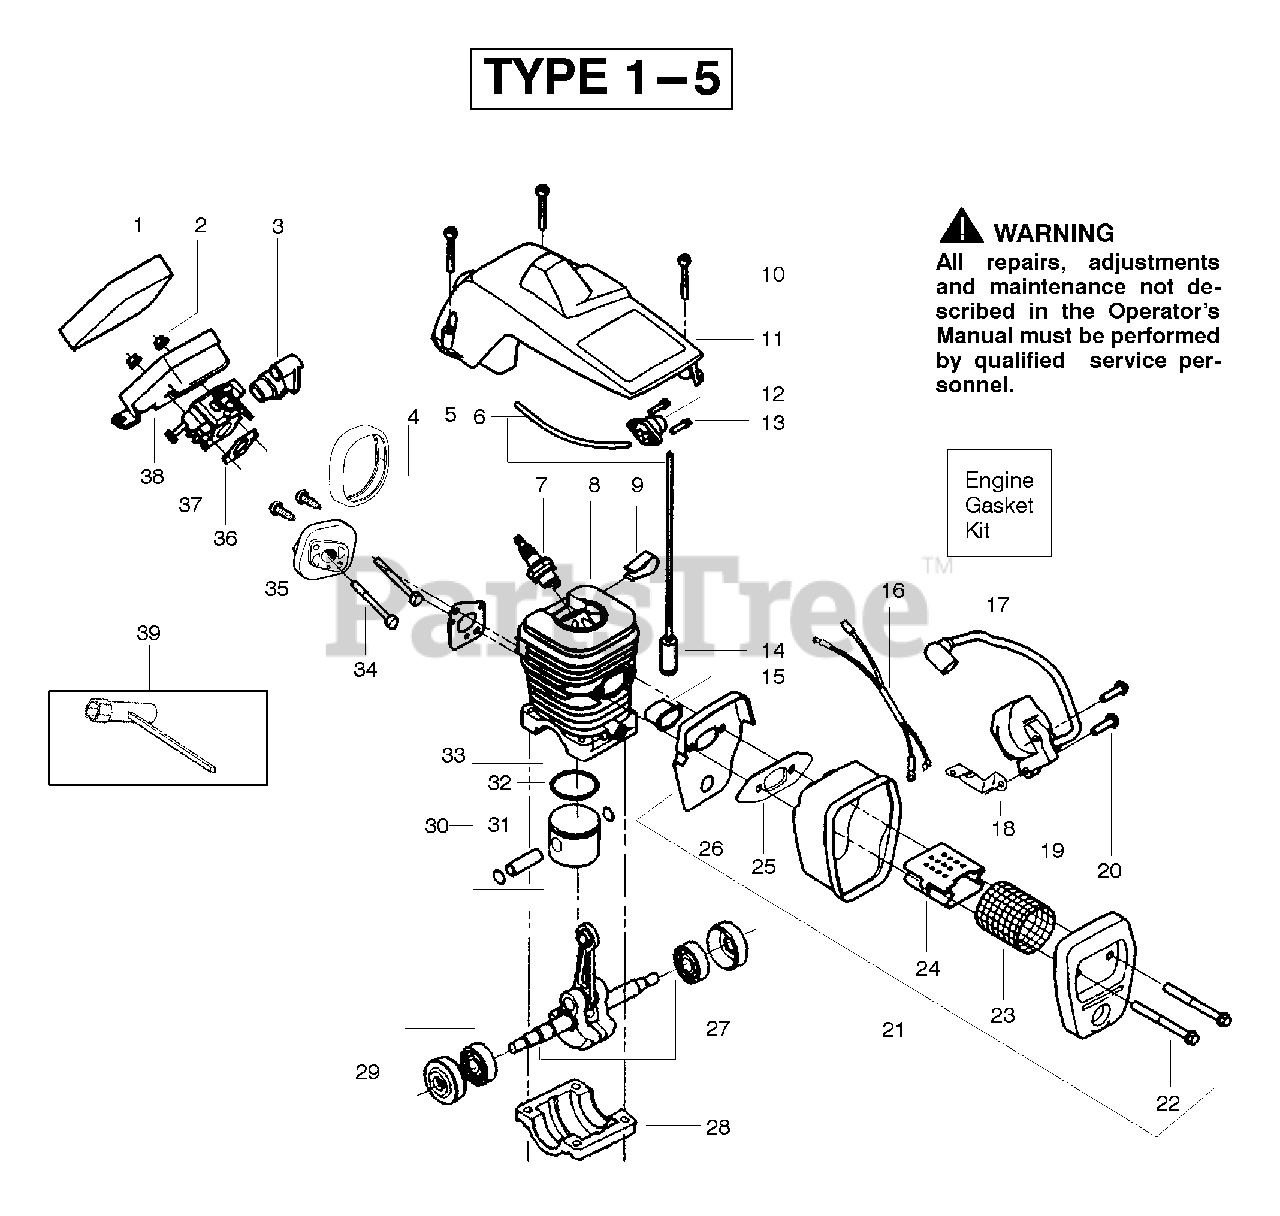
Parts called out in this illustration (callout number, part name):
1	Foam-Air Filter
3	Grommet-Carb Adjust
4	Seal-Carb Adapter
5	Carb. Adapter
6	Fuel Line Kit (Small)
7	Spark Plug (RCJ-7Y)
8	Kit-Cylinder
9	Clip-High Tension Lead
11	Cylinder Shield
12	Air Purge Ass'y.
14	Fuel Pick-up Ass'y.
15	Heat Insulator
16	Assy.-Wire Harness
17	Kit-Engine Gasket
18	Strap-Ground
19	Module-Ignition
21	Assy-Muffler
23	Screen-Spark
24	Diffuser-Muffler
25	Gasket-Muffler (kit)
26	Backplate-Muffler
27	Assy.-Crankshaft
28	Cap-Crankcase
29	Assy.-Seal & Bearing
30	Kit-Piston
31	Retainer-Piston Pin
32	Ring-Piston
33	Gasket-Carb. Adap. (kit)
36	Gasket-Carb. (kit)
37	Kit-Carburetor (WT-324)
38	Housing-Air Filter
39	Wrench-Bar
